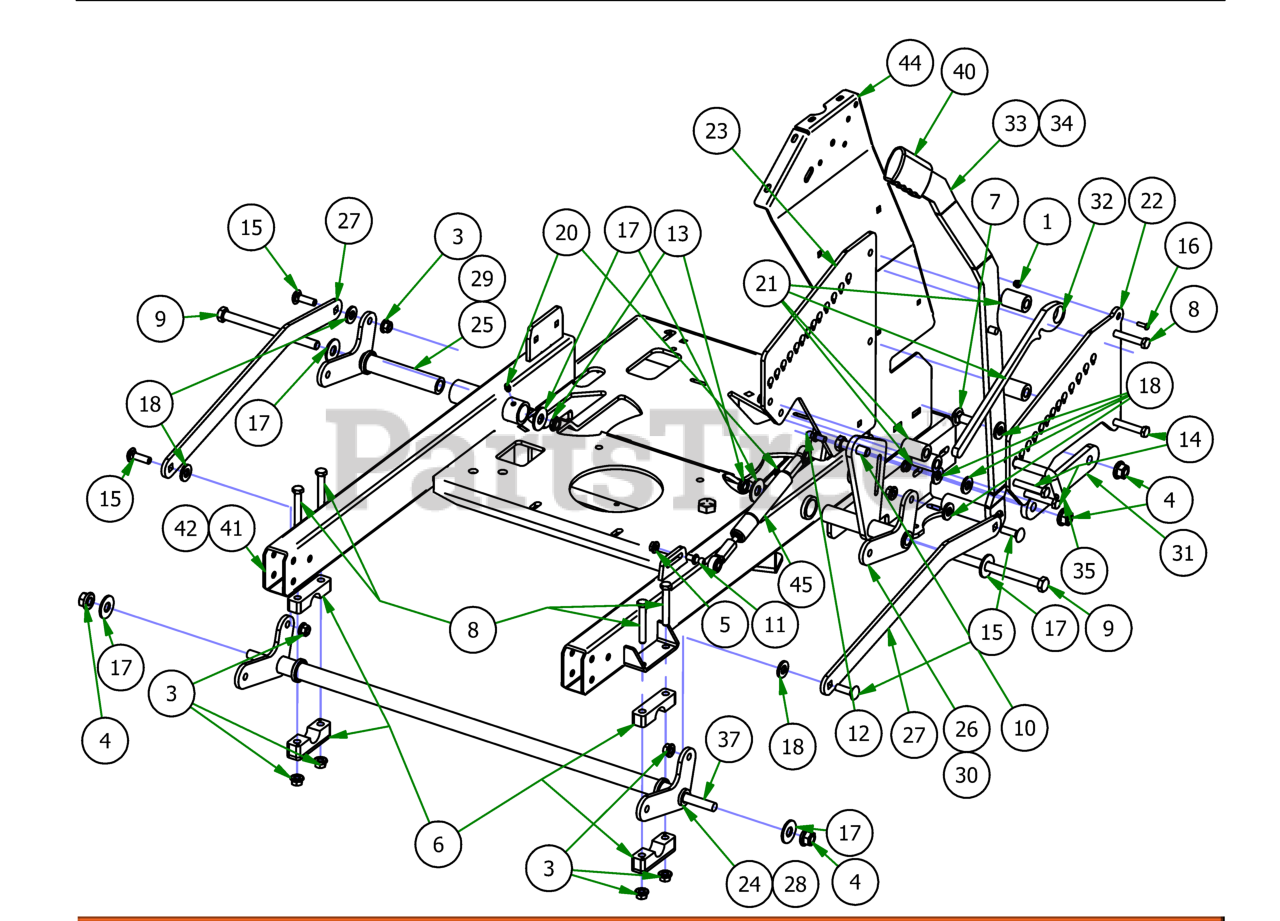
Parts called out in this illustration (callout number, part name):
1	10-24 Nylon Insert Locknut Zinc
3	3/8 Nylock Flange Nut
4	1/2-13 NYLON INSERT FLANGE LOCKNUT ZINC
5	5/16-18 Hex Flange Nuts Zinc w
6	Pillow Block Kit
7	1/2-13 X 1-1/2 CARRIAGE BOLT (GR.5) ZINC
8	3/8-16 X 2-1/2 HEX CAP SCREW (GR.5) ZINC
9	1/2-13 X 6 1/2 HEX CAP SCREW (GR.5) ZINC
10	1/2-13 x 1 3/4" GR5 Hex Bolt
11	10mm Damper Ball Stud-Steering
12	10mm Damper Ball Stud-XP Linkage
13	1/2-13 NYLON INSERT JAM LOCKNUT ZINC
14	3/8-16 X 3 HEX CAP SCREW (GR.5) ZINC
15	3/8-16 X 1-1/4 Carriage Bolt
16	10-24 X 5/8 BS C/S 18-8 SS
17	1/2 Flat Washer
18	.505 ID X 1.000 OD X .125 THICK FLAT WASHER NYLON
20	1/4" Press in Grease Fitting
21	.502 ID X .750 OD X 1.500 Long Spacer
22	2019 Stand On Outer Adjustment Plate
23	2019 Stand On Inner Adjustment Plate
24	2019 Stand On Front Actuator Bar Weldment
25	2019 Stand On Actuator Bar Rear RH
26	2019 Stand On Actuator Bar Rear- LH
27	2019 Stand-on Actuator Linkage
28	2020 36 Stand On Front Actuator Bar Weldment
29	2020 36 Stand On Actuator Rear RH
30	2020 36 Actuator rear_LH
31	2019 Stand On Lever Secondary Linkage
32	2019 Stand on deck lever lock
33	2019 Stand On Lift Lever Weldment
34	2020 36 Stand On Lift Lever Weldment
35	Height Adj Pin
36	2018 Maverick Turnbuckle (Top Link) (36" ONLY)
37	2020 36 Stand On Turnbuckle Rod
40	2019 Stand On Lift Grip
41	2019 Stand On Frame Weldment
42	2020 36 Stand On Frame Weldment
44	2019 Podium Panel Left
45	200 lb Gas Spring- 54" Deck outlaw
